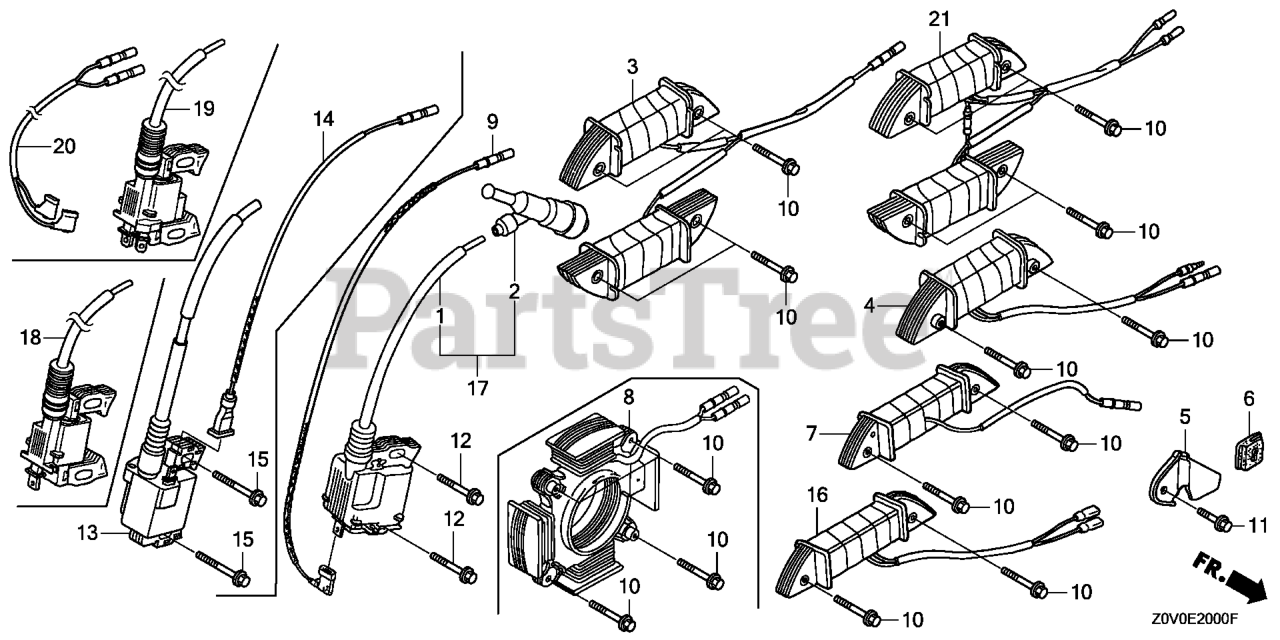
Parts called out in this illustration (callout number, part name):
2	CAP ASSY., NOISE SUPPRESSOR (TEC)
9	WIRE, STOP SWITCH (370MM)
12	BOLT, FLANGE (6X25) Use up to Engine SN 2056819.
18	COIL ASSY., IGNITION (TEC)
